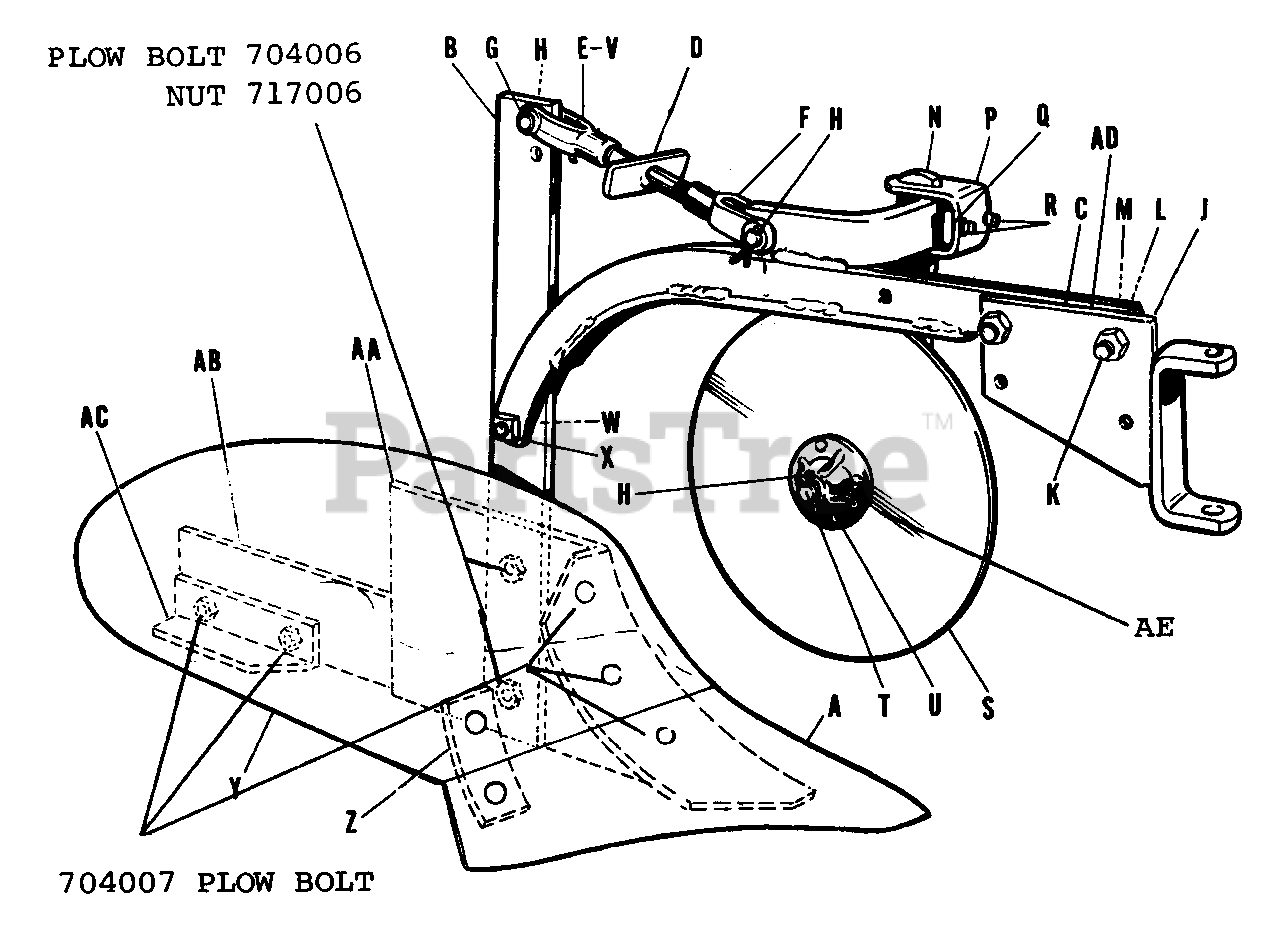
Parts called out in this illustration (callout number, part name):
C	Beam Assembly, Plow
D	Yoke Rod Assembly
E	Yoke, L.H.
F	Yoke, R.H.
G	Pin, Yoke
H	Pin, Cotter, w/extended prong, 1/8" dia. x 1" lg.
J	End Assembly, Plow Beam
K	Capscrew, Hex Hd., 3/8"-16 x 2-1/4" lg.
L	Washer, Lock, 3/8"
M	Nut, Full Hex., 3/8"-16 NC
N	Standard, Coulter
Q	Nut, Special, 5/16" x 1" x 2 1/4" lg.
R	Set Screw, Cup Point, Sq. Hd., 3/8"-16 NC x 1" lg.
S	Coulter Assembly, w/bushing
T	Spindle, Coulter
V	Nut, Hex, Jam, 5/8"-11 NC
W	Screw, Cap, Hex., 1/2"-13 NC x 1 3/4" lg.
X	Nut, Hex., Full, 1/2"-13 NC
Y	Moldboard
Z	Brace, Moldboard
AC	Angle, Slip Heel
AD	Spacer, Plow Beam
AE	Bushing, Coulter
